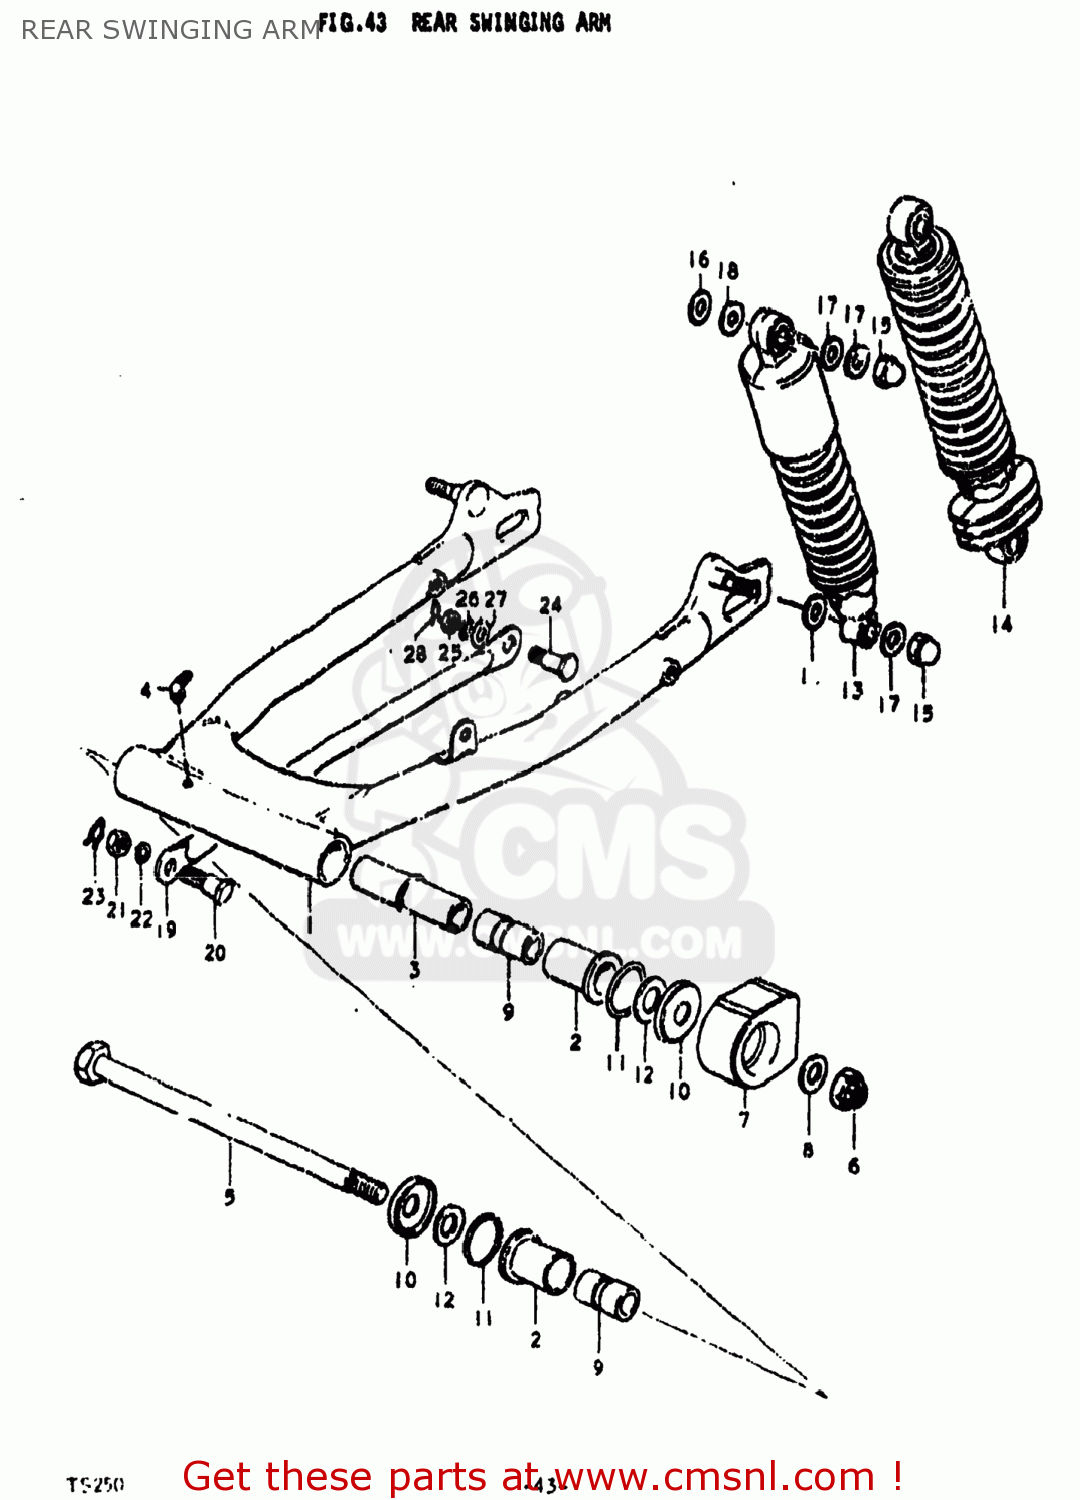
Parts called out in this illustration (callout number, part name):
1	SWING ARM ASSEMBLY,REAR
2	BUSHING
3	SPACER,SWING ARM,CENTER
4	NIPPLE,GREASE
5	SHAFT,REAR SWING ARM
6	NUT
7	BUFFER,CHAIN TOUCH DEFLECTOR
8	WASHER
9	SPACER,RR SWGARM PIVOT
10	COVER, DUST SEAL
11	O RING(D:2,ID:24.5)
12	WASHER(12.5X24X2.3)
13	ABSORBER ASSEMBLY,REAR SHOCK
14	ABSORBER ASSEMBLY,REAR SHOCK
15	NUT
16	WASHER
17	WASHER
18	WASHER (12.5X24X1.6)
19	TORQUE LINK,REAR
20	BOLT(8X22.5)
21	NUT
22	LOCK WASHER
23	CLIP
24	BOLT
25	NUT
26	LOCK WASHER
27	WASHER (12.5X24X1.6)
28	SPRING,RETAINER
